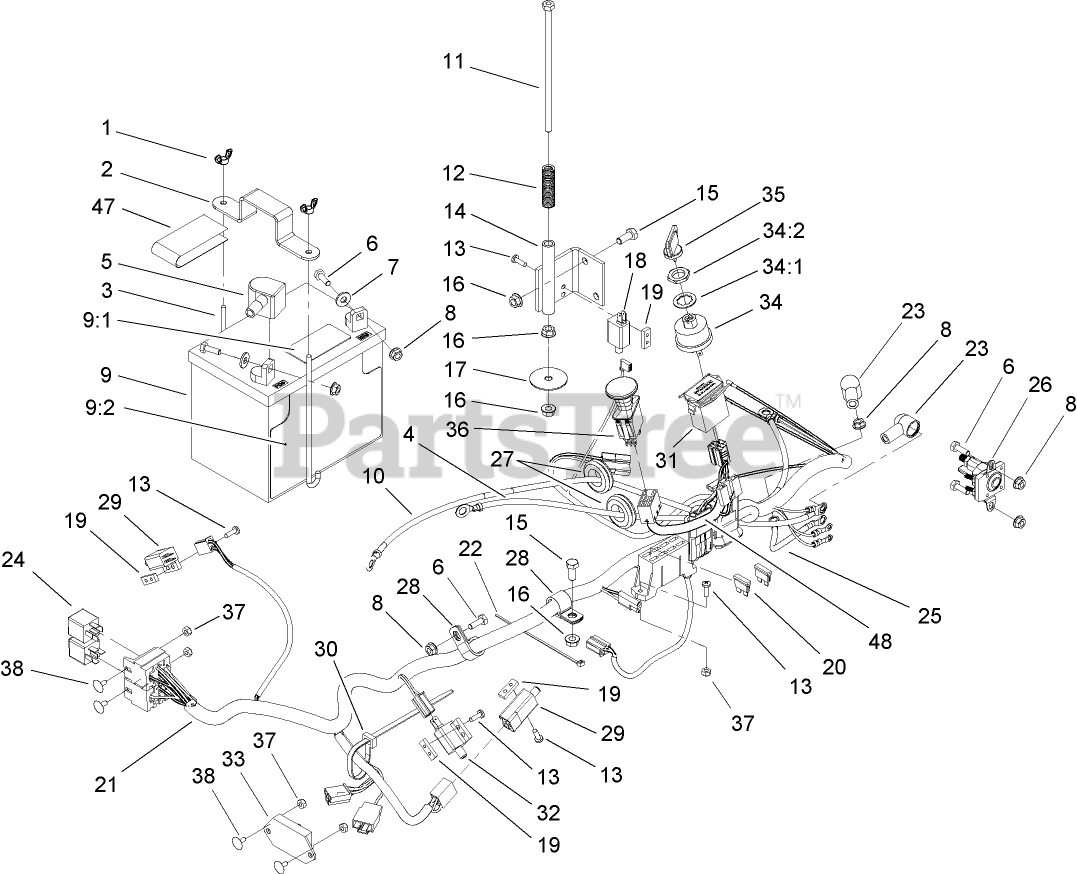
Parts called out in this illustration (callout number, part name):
1	WINGNUT
2	STRAP-HOLDDOWN
3	BOLT-HOLDDOWN
4	CABLE-GROUND, NEGATIVE
5	INSULATOR-BATTERY
6	SCREW-HH
7	WASHER-FLAT
8	NUT-HF
9	BATTERY
9:1	Decal-Battery
9:2	Decal-Battery
10	CABLE-BATTERY, POSITIVE
11	SCREW-HH
12	SPRING-SWITCH, SEAT
13	SCREW-HEAD, TRUSS
14	BRACKET-SWITCH, SEAT
15	SCREW-HH
16	NUT-HF
17	WASHER
18	SWITCH-CLOSED, NORMALLY
19	PLATE-TAPPED
20	FUSE-BLADE TYPE, 20 AMP
21	HARNESS-ELECTRICAL
22	TIE-CABLE
23	INSULATOR-SOLENOID
25	CABLE-STARTER, POSITIVE
26	SWITCH-SOLENOID
27	GROMMET
28	CLIP-LOOM
29	SWITCH-OPEN, NORMALLY
30	TIE-PLASTIC
31	METER-HOUR
32	SWITCH
33	MODULE-DELAY, SEAT
34	Key Switch ASM
34:1	WASHER-TOOTH, INTERNAL
34:2	NUT-HH
35	KEY-IGNITION
36	SWITCH-DELTA
37	NUT-LOCK, NI
38	BOLT-CARR
47	DECAL-INSTRUCTIONS, CHARGING
48	HARNESS-ELECTRICAL, CONTROL PANEL
